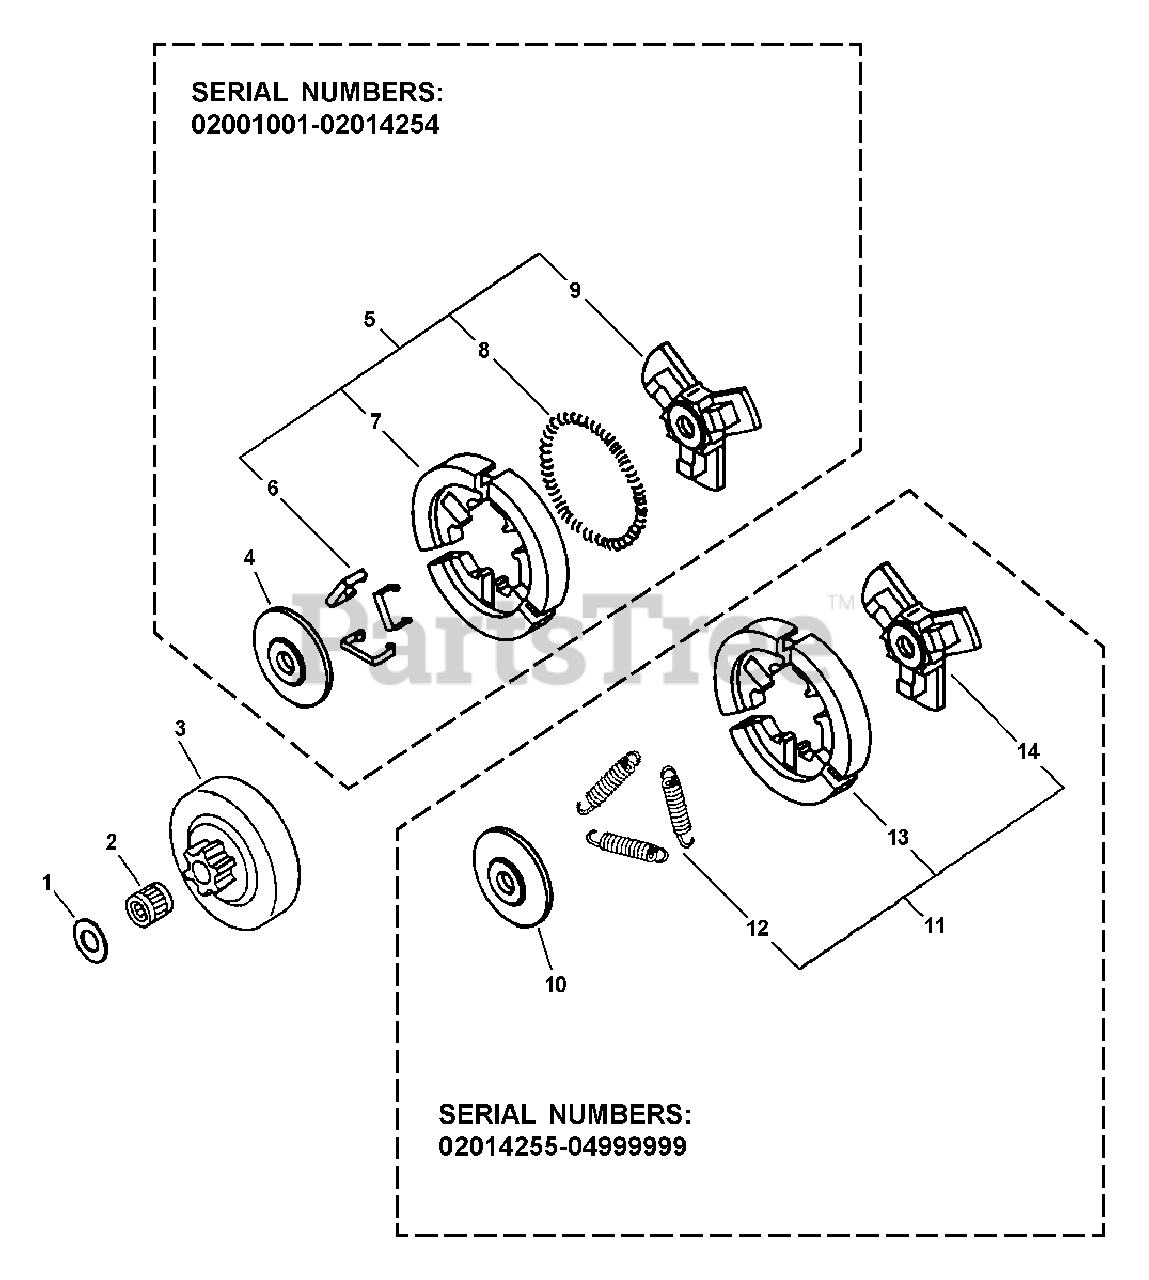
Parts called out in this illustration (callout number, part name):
1	WASHER 10.2×24.5×1.2
2	BEARING, NEEDLE 10×13×10
3	DRUM, CLUTCH 3/8"
4	PLATE, CLUTCH
5	CLUTCH ASSY
6	SPRING, FLAT
7	SHOE SET, CLUTCH (3PCS)
8	SPRING, TORSION
9	HUB, CLUTCH
10	PLATE, CLUTCH
11	CLUTCH ASSY
12	SPRING, CLUTCH
13	SHOE SET, CLUTCH (3PCS)
14	HUB, CLUTCH
